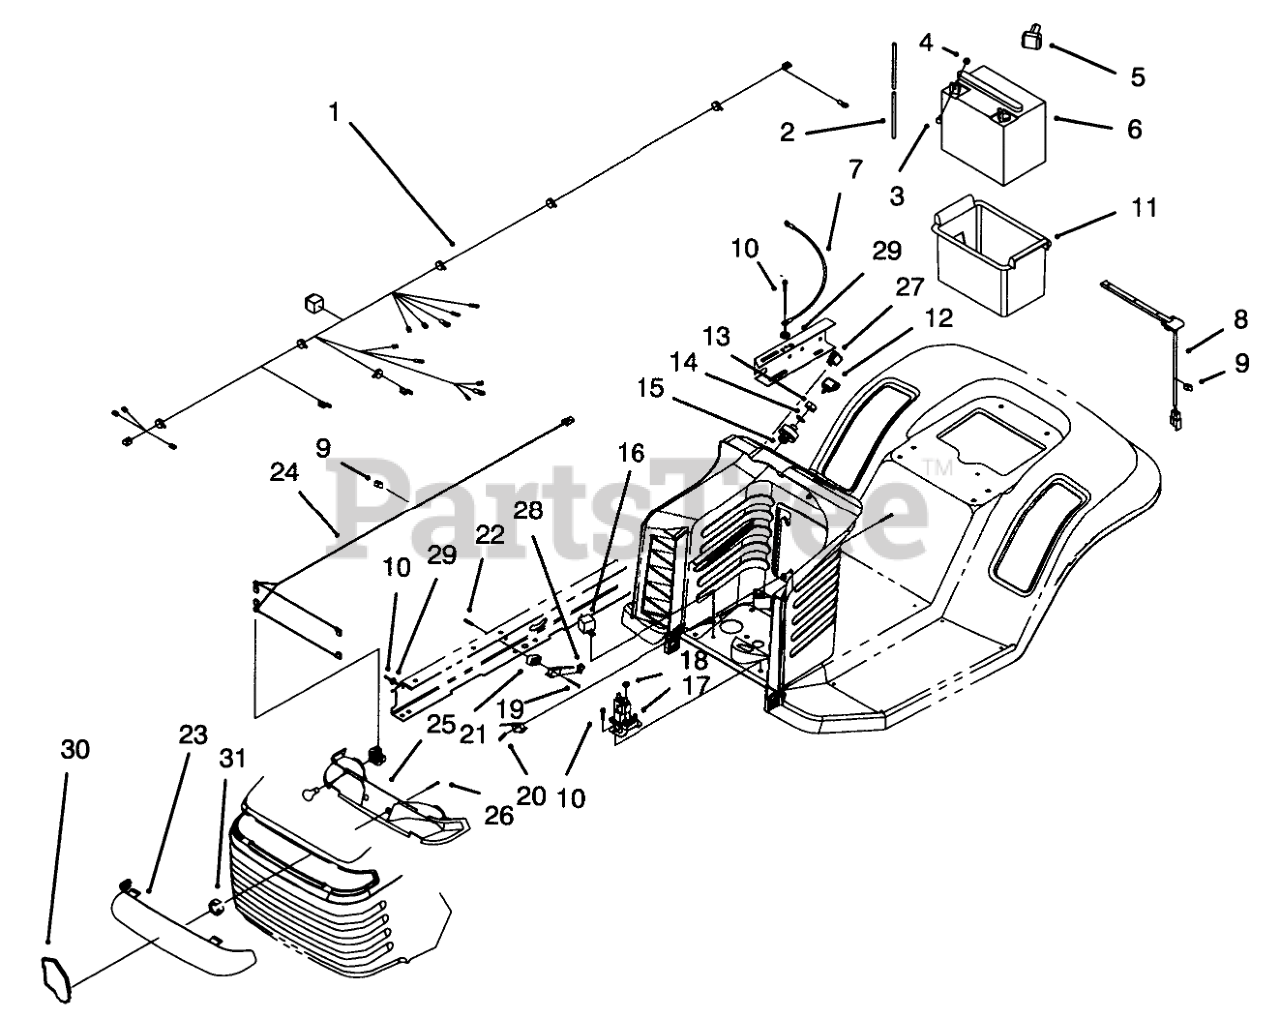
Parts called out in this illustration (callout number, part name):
1	Harness-Wire
2	TUBE-BATT DRAIN/80-2600
3	SCREW-HH
4	NUT-WING
5	BOOT-TERMINAL
6	Battery
7	WIRE ASM
8	SWITCH-SEAT
9	CLIP-RETAINER, WIRE
10	SCREW-HWH
11	BOX-BATTERY
12	KEY-IGNITION
13	NUT-HH
14	WASHER-TOOTH, INTERNAL
15	Key Switch ASM
16	RELAY
17	Solenoid
18	NUT-KEPS
19	Screw
20	SWITCH-MICRO
21	SPACER
22	NUT-SPEED
23	LENS-HEADLIGHT
24	HARNESS-WIRE, LIGHTS
25	HEADLIGHT REFLECTOR ASM
27	SWITCH-ROCKER
28	PLUNGER-SEAL
29	WASHER-LOCK/EXT
30	EMBLEM-GRILLE WHEELHORSE
